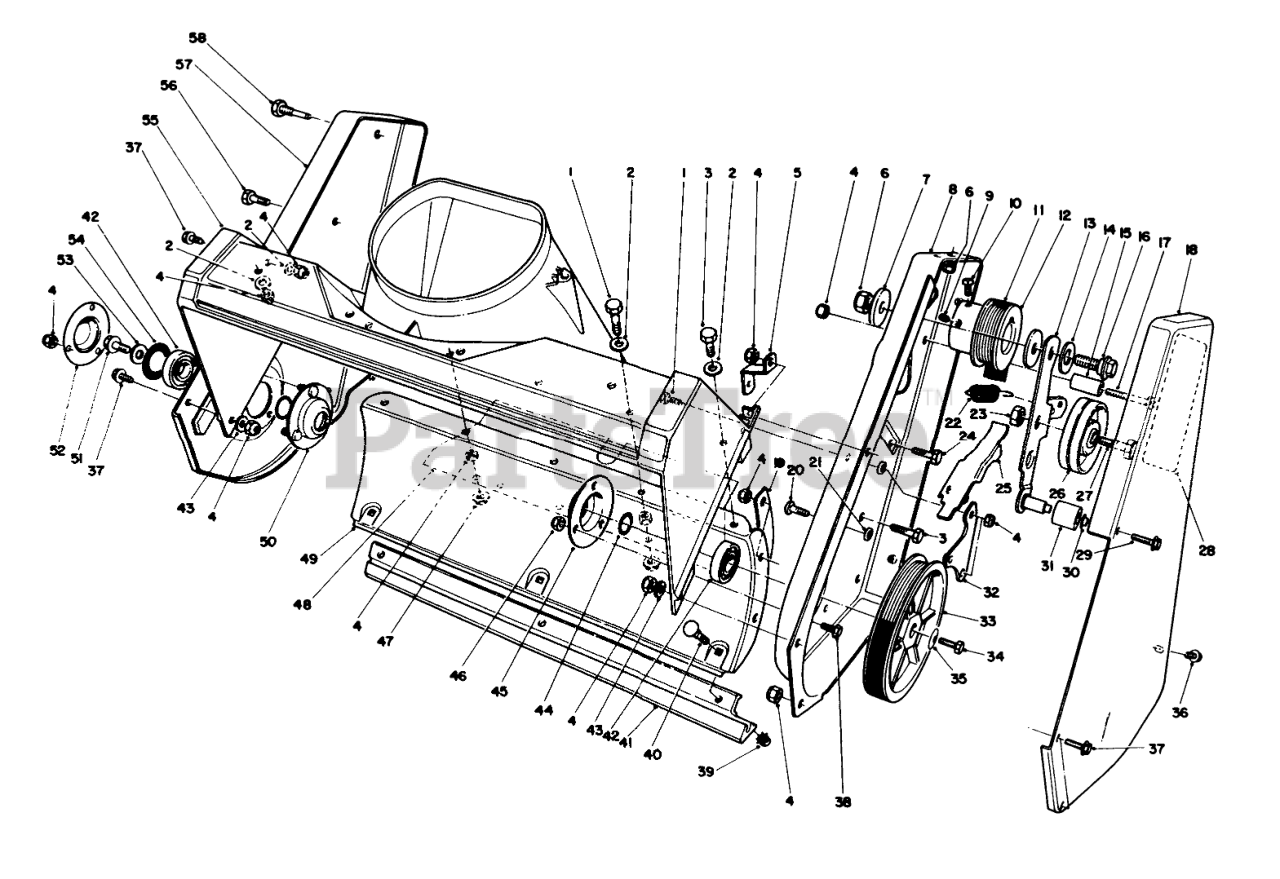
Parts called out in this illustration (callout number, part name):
1	SCREW-HH
2	WASHER-FLAT
3	SCREW-HH
4	NUT-LOCK, NI
5	BRACKET-HOUSING
6	NUT-LOCK, NI
7	WASHER-PIVOT
8	Sideplate-LH
9	SCREW-HSH
10	SCREW-SQH
11	BELT - DRIVE
12	ENGINE PULLEY
13	Idler Arm Assembly (Incl. Ref. #30 & 31)
14	WASHER
15	SLEEVE-GUIDE, BELT
16	SCREW-SHOULDER
17	SCREW-HH
18	Cover-Drive
19	BRACKET-HOUSING, LOWER
20	SCREW-HSBH
21	SPACER-PLATE, PIVOT
22	SPRING-EXTENSION
23	NUT-LOCK, CONE
24	SCREW-HH
25	BRAKE-ARM
26	PULLEY-IDLER
27	SCREW-HH
28	DECAL
29	SCREW-HWH, TAP
30	NUT-PUSH
31	ROLLER-BRAKE
32	PIVOT PLATE ASM
33	ROTOR PULLEY ASY
34	SCREW-HH
35	WASHER-BELLEVILLE
36	SCREW
37	SCREW-HWH
38	SCREW-SHH
39	NUT-KEPS
40	SCREW-CARR
41	SCRAPER
42	BEARING-BALL
43	WASHER-FLAT
44	WASHER-THRUST
45	FLANGE-BEARING
46	NUT-LOCK, NI
47	NUT-LOCK, HHF
48	COVER-BOTTOM
49	Housing-Lower
50	FLANGE-BEARING
51	SCREW-HHF
52	Trough
53	WASHER-FLAT
54	WASHER-RUBBER
55	HOUSING
56	SCREW-HH
57	Sideplate-RH
58	PIN-ROTOR
